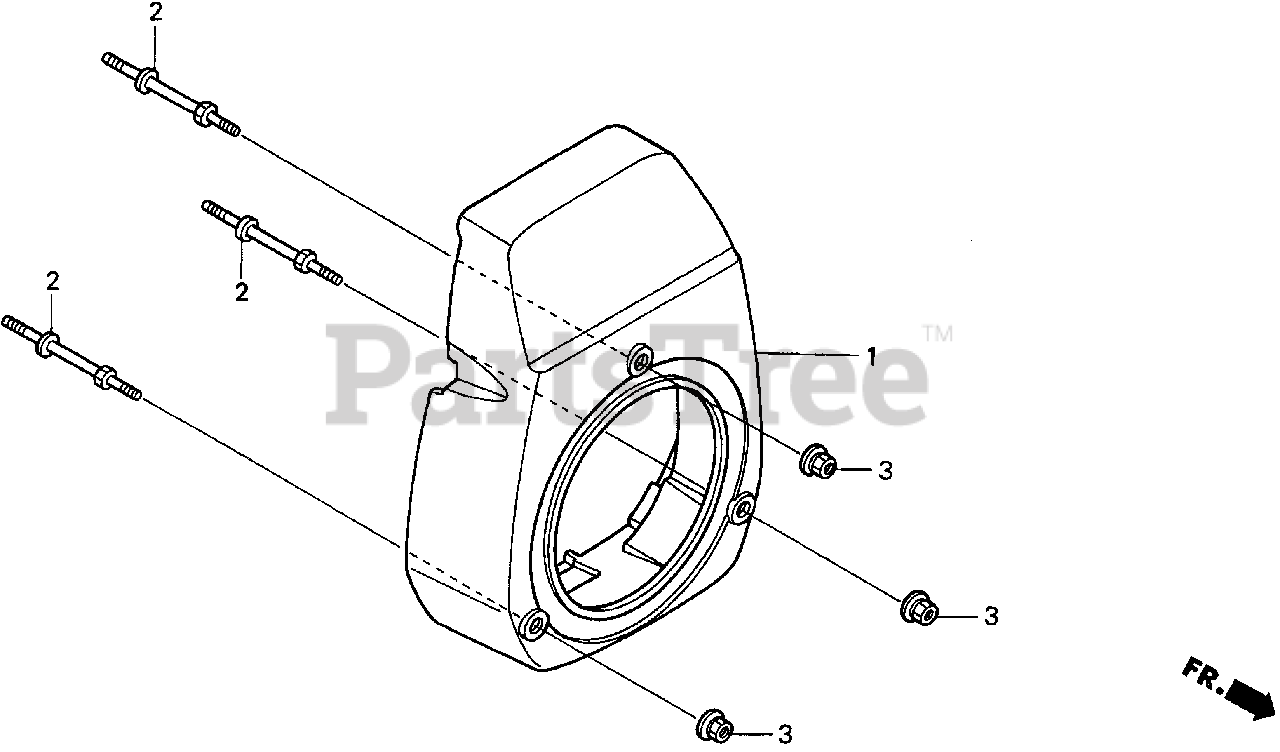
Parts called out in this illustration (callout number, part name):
1	COVER, FAN *NH1* (BLACK)
2	BOLT, STUD
3	NUT, FLANGE (6MM)
